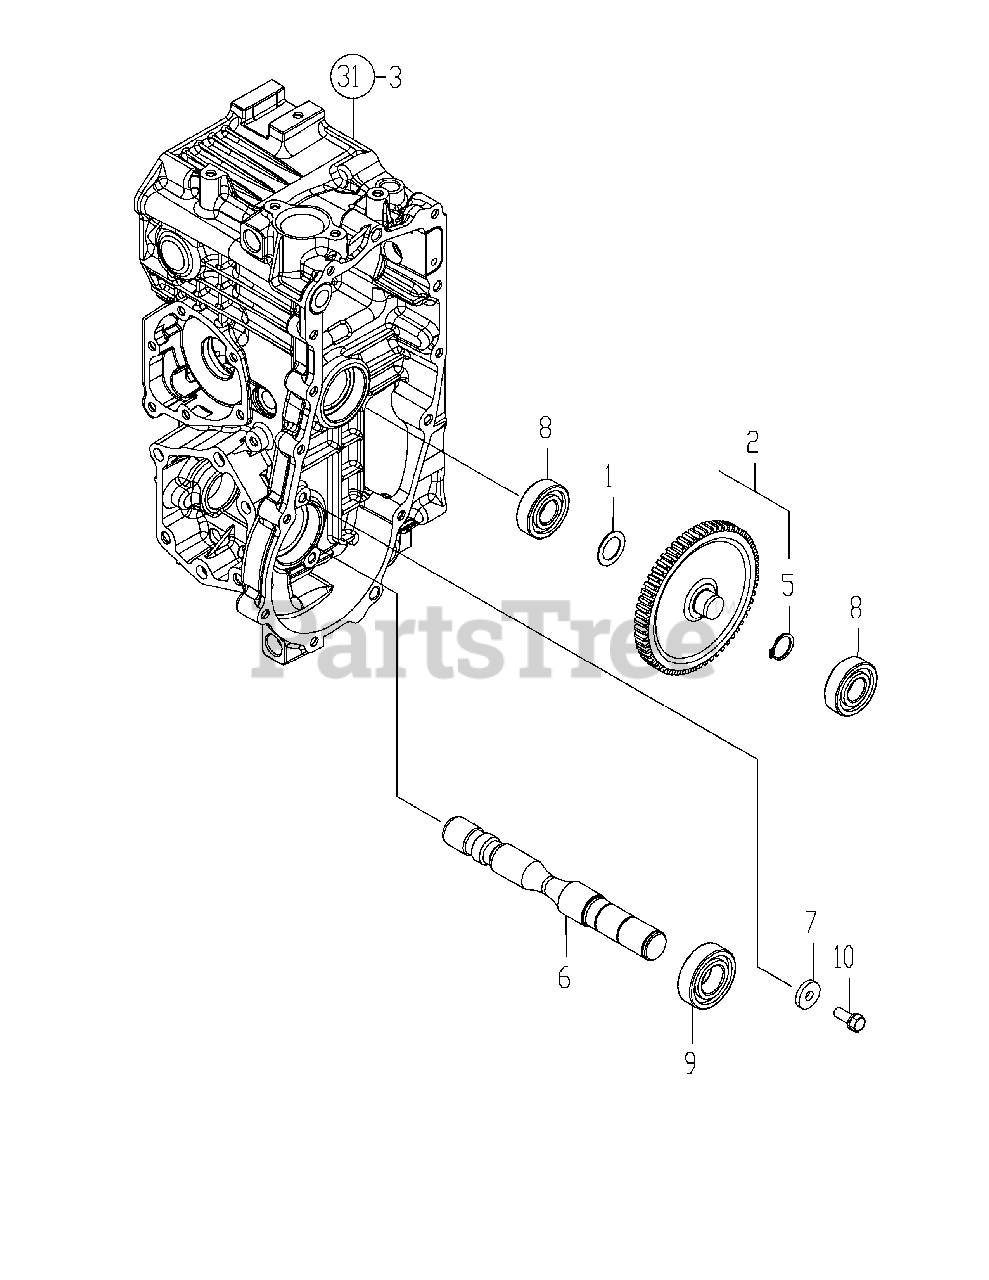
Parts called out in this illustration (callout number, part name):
2	IDLE ASSY, PTO
6	SHAFT, MID PTO
7	WASHER, 8.5X24X4
9	BEARING, 6205 NTN
